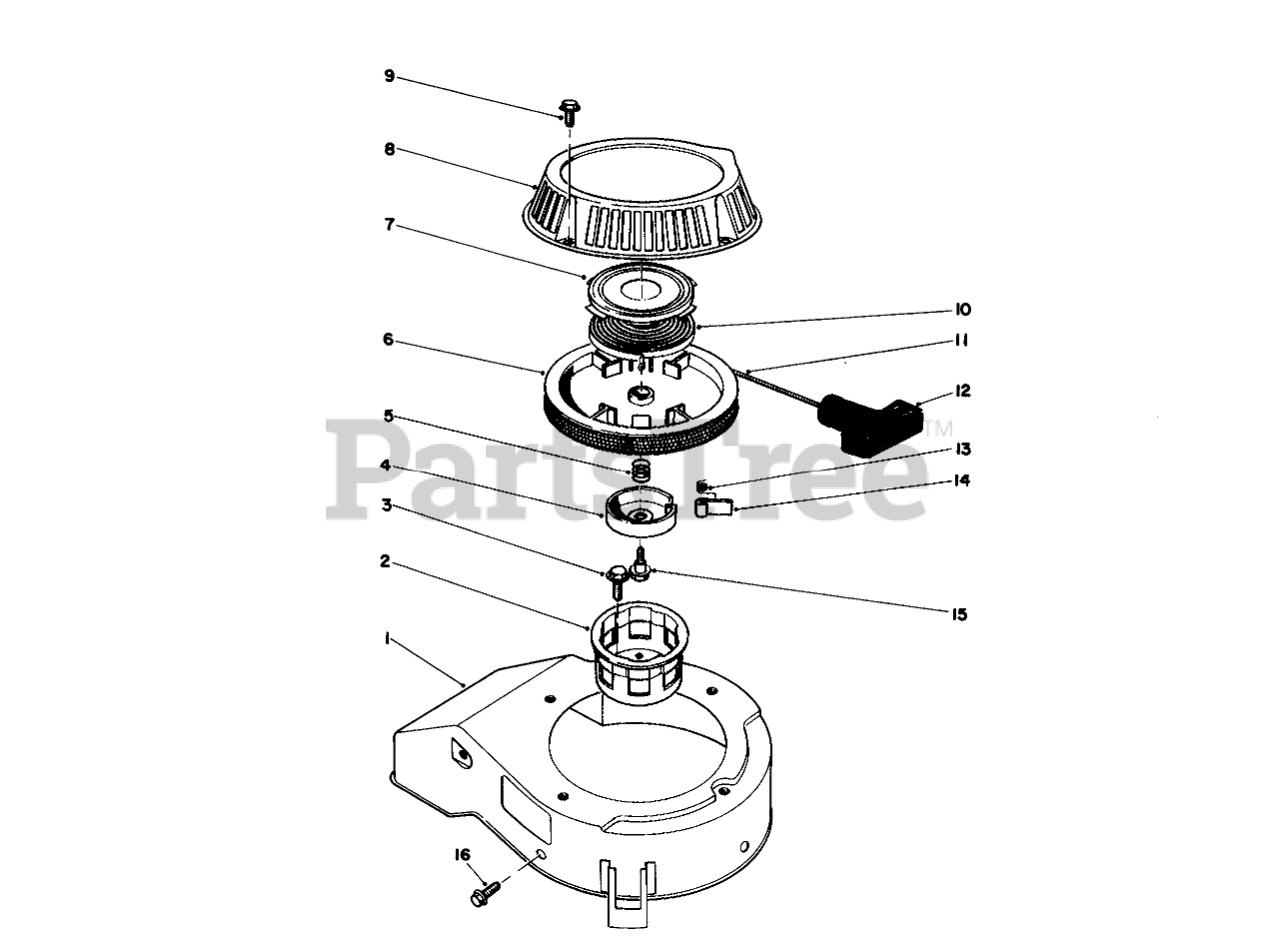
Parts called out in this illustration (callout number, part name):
1	COVER
2	CUP - STARTER
4	RETAINER
5	SPRING
7	Retainer-Recoil Spring
9	SCREW-HHF
10	Spring-Recoil
11	ROPE-STARTER
12	HANDLE-RECOIL
13	SPRING
